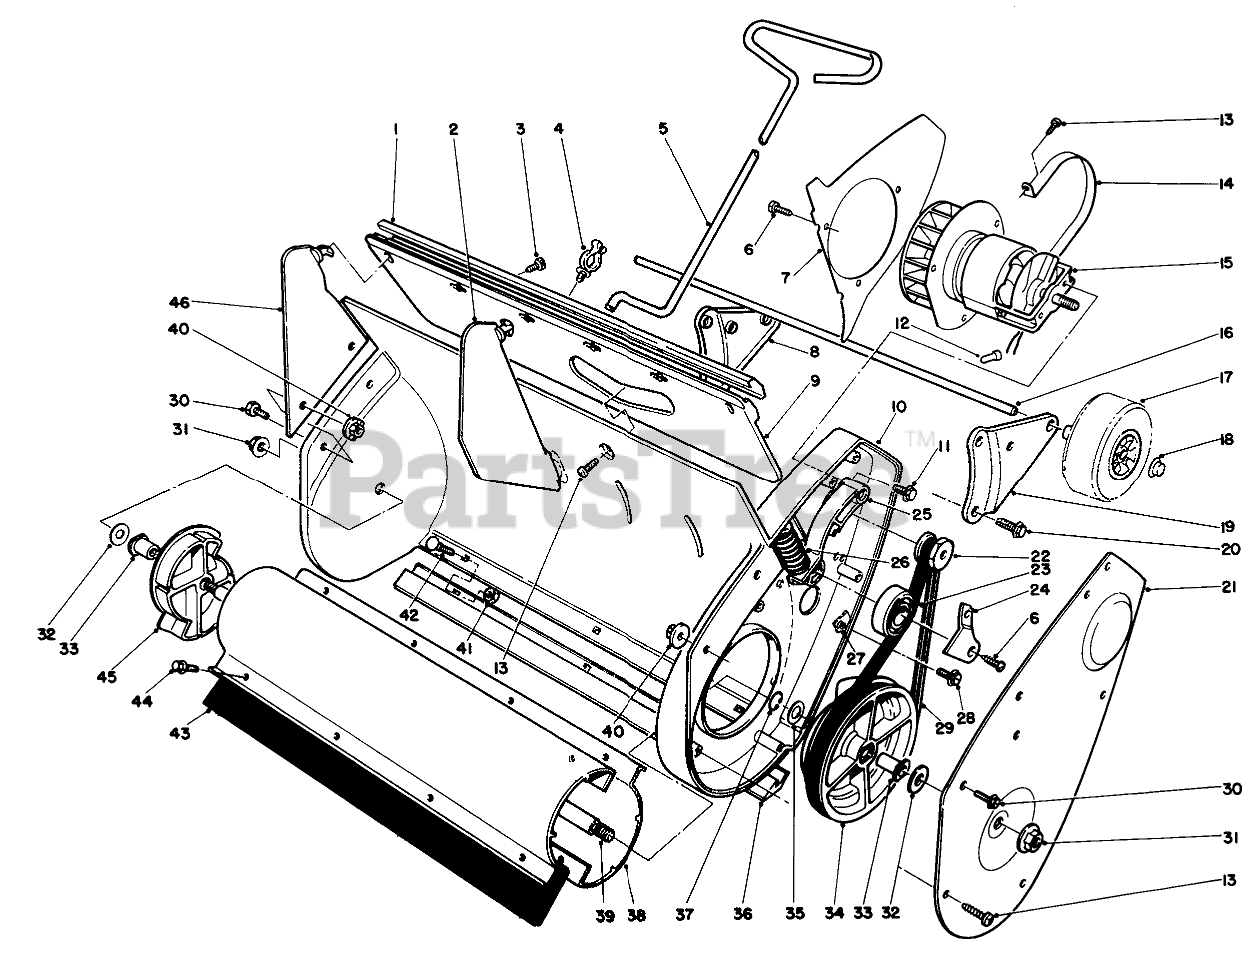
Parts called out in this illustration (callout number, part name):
1	MOULDING
2	INNER VANE
3	10-16 X 3/8 THDG SCREW
4	Wire Keeper
5	ROD, VANE ADJUSTING
6	#8 X .625" PHILPS PAN H
7	AIR BAFFLE
8	Bracket R.H.
9	Vane Mount
10	Housing
11	SCREW-HH
12	CONNECTOR WIRE JOINT
13	Screw
14	MOTOR STRAP
15	MOTOR, 1200 PWR CURVE
16	AXLE SHAFT
17	S-120 WHEEL
18	PUSHNUT-CAP, WASHER
19	Wheel Bracket L.H.
20	Screw
21	Cover-Belt Case
22	PULLEY DRIVE
23	Bearing-Ball
24	1200 PC-IDLER PULL. RET
25	1200 PC-IDLER ARM
26	SPRING
27	NUT-TYPE J
28	SCREW-HWHTF
29	BELT - DRIVE
30	SCREW-HWH
31	NUT-HF
32	THRUST WASHER (THICK)
33	BUSHING-ROTOR
34	Pulley-Driven
35	WASHER-THRUST
36	SCRAPER-SERVICE
37	RING-RETAINING
38	ROTOR, S-120 COST REDUC
39	SHAFT-ROTOR
41	NUT-KEPS
42	SCREW-CARR
43	ROTOR BLADE, S-120 CR
44	TSCREW-HWH
45	END CAP-ROTOR
46	OUTER VANE
